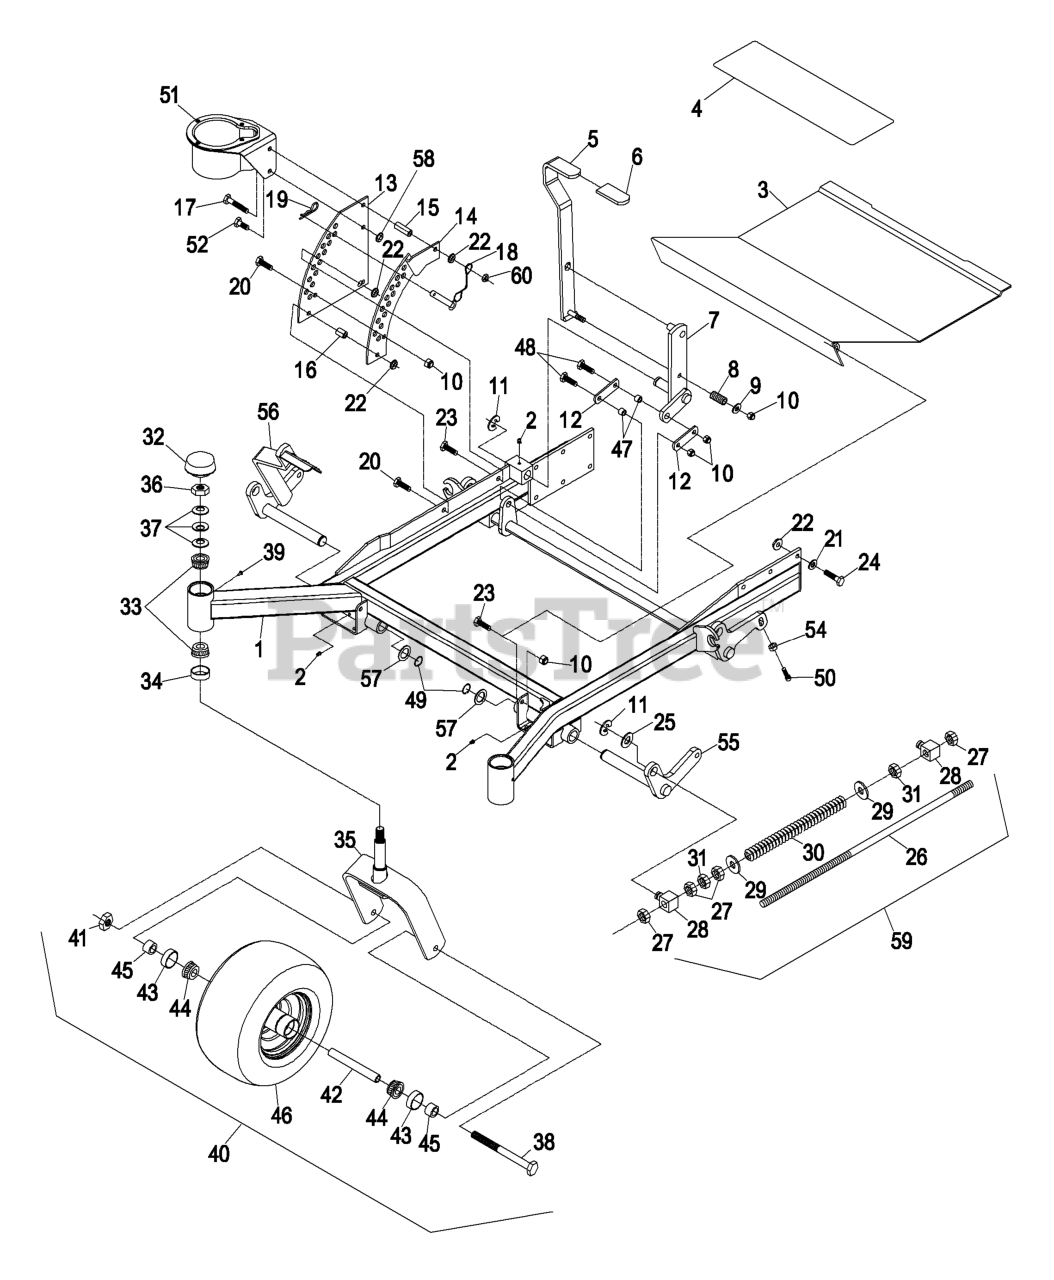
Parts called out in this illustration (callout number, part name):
2	FITTING-GREASE
4	PAD-ANTISKID
5	LIFT LEVER/GRIP ASM
6	GRIP-LEVER, LIFT
7	ARM-LIFT, DECK
8	SPRING-COMPRESSION
9	WASHER-FLAT
10	NUT-LOCK, NI
11	RING-RETAINING, EXT
12	ARM-LIFT, DECK
13	PLATE-LIFT, DECK
14	PLATE-LIFT, DECK
15	BUSHING-LEVER, LIFT
16	BUSHING-LEVER, LIFT
17	SCREW-HH
18	PIN-HITCH (W/LANYARD)
19	PIN-COTTER
20	SCREW-HH
21	WASHER-BELLEVILLE
22	NUT-HHF, WHIZ
23	SCREW-HH
24	SCREW-HH
25	WASHER-FLAT
26	ROD-LIFT, DECK
27	NUT-HEX
28	SWIVEL-DECK MOUNT, REAR
29	WASHER-FLAT
30	SPRING-SUPPORT, DECK
31	NUT-JAM
32	CAP-GREASE
33	Cone-Bearing Tapered Roller
34	SEAL-GREASE
36	NUT-LOCK, NI
37	WASHER-BELLVILLE
38	SCREW-HH
41	NUT-LOCK, NI
42	SPACER-CASTER, FRONT
43	SEAL-CASTER
44	BEARING-CONE, TAPERED ROLLER
45	SPACER-BEARING
47	BUSHING
48	SCREW-HH
49	RING-RETAINING
50	SCREW-HSH
52	SCREW-HH
54	NUT-JAM
55	WLD, FRONT LIFT SHAFT - L
56	WLD, FRONT LIFT W/ LEVER
57	WASHER-SPACER
59	FRONT FRAME SPRING ASM
